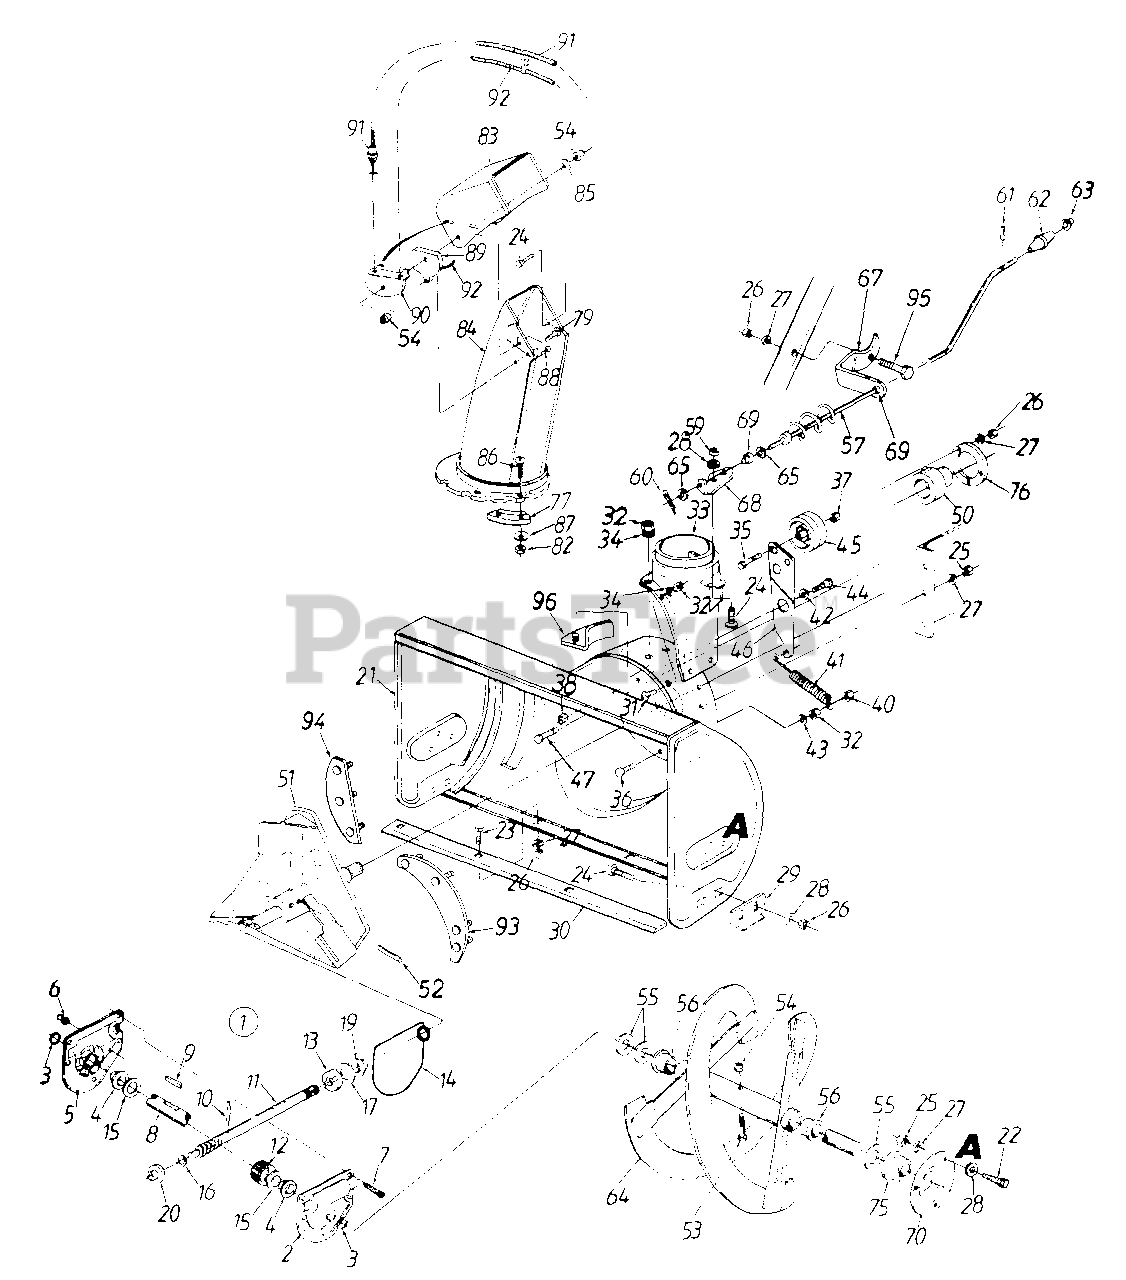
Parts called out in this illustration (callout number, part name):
1	Worm Drive Ass'y. Comp.
2	Reducer Housing - L.H.
4	Flange Bearing .75" I.D.
5	Reducer Housing - R.H.
6	Grease Fitting
7	Hex TT-Tap Scr. 1/4-20 x .75" Lg.
8	26" Auger Shaft
9	#61 Hi-Pro Key 3/16" x 5/8" Dia.
10	Spiral Pin 1.25" Lg.
11	Impeller Shaft
12	Worm Gear
13	Thrust Collar
14	"O"-Ring (Special)
15	Fl-Wash. .76" I.D. x 1.5" O.D.
16	Fl-Wash. .5" I.D. x 1" O.D.
17	Fl-Wash. .76" I.D. x 1.49" O.D.
19	Flange Bearing .75" I.D.
20	Flange Bearing .503" I.D.
21	26" Auger Housing Ass'y.
22	Hex Bolt 5/16-24 x .75" Lg.
23	Carriage Bolt 5/16-18 x .62" Lg.
24	Carriage Bolt 5/16-18 x .75" Lg.
25	Hex Nut 5/16-24 Thd.
26	Hex Nut 5/16-18 Thd.
27	L-Wash. 5/16" I.D.
28	Bell-Wash. .345" I.D. x .88" O.D.
30	26" Shave Plate
31	Truss Mach. Scr. 1/4-20 x .5" Lg.
32	Hex Nut 1/4-20 Thd.
33	Chute Adapter
34	Spring Washer 1/4" I.D.
35	Hex Bolt 3/8-24 x 1.5" Lg. (Gr. 5)
36	Hex Bolt 1/4-20 x .75" Lg. (Gr. 5)
37	Hex Ins. L-Nut 3/8-24 Thd.
38	Hex Top L-Nut 3/8-16 Thd.
40	Hex L-Nut 1/4-20 Thd.
41	Ext. Spring 3.6" Lg.
42	Fl-Wash. 5/8" I.D. x 1.25"
43	L-Wash. 1/4" I.D.
44	Shld. Bolt .625" Dia. x .170" Lg.
45	Fl-Idler 2.75" O.D.
47	Hex Bolt 5/16-18 x 5/8" Lg.
50	Ball Bearing .75" I.D.
52	Spiral Pin 1.5" Lg.
53	Shear Bolt 5/16-18 x 1.5" Lg.
54	Hex Cent. L-Nut 5/16-18 Thd.
55	Fl-Wash. .76" I.D. x 1.49"
56	Flange Bushing .8" I.D.
57	Chute Crank Ass'y.
59	Hex Ins. L-Nut 5/16-18 Thd.
60	Cotter Pin 3/32" Dia. x .75"
61	Roll Pin 1/8" Dia. x .63" Lg.
62	Chute Crank Knob
64	Spiral Ass'y. - L.H.
65	Fl-Wash. .385" I.D. x .62" O.D.
69	Plastic Bushing .38" I.D.
75	Plastic Bearing w/Flats
76	Bearing Housing
77	Chute Flange Keeper
79	Carriage Bolt 5/16-18 x 1.5" Lg.
82	Hex L-Nut 1/4-20 Thd.
83	Upper Chute
84	Lower Chute
85	Fl-Wash. .344" I.D. x 1.125"
86	Truss Mach. Scr. 1/4-20 x .75" Lg.
87	Fl-Wash. 1/4" I.D.
88	Hex AB-Tap Scr. 1/4 x .62" Lg.
89	Cable Guide
91	Chute Control Cable
92	Chute Control Cable w/Clip
96	Chute Reinforcement
